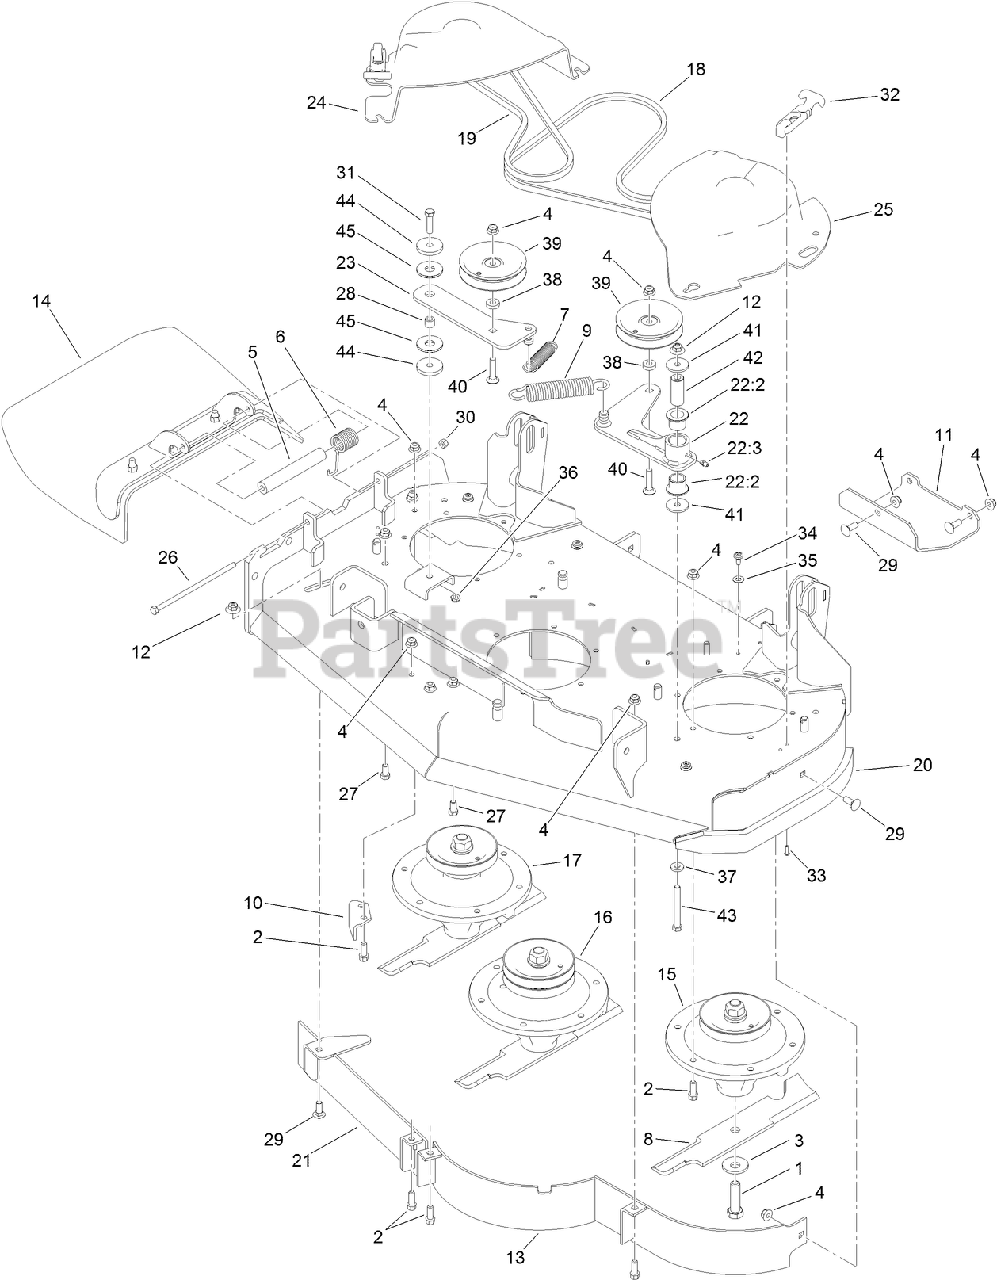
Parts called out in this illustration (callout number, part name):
1	SCREW-BLADE
2	SCREW-HWH
3	Washer-Blade Bolt, Heavy
4	NUT-HF, NI
5	SPACER
6	SPRING-TORSION
7	SPRING-EXTENSION
8	BLADE-14 INCH (HIGH SAIL)
9	SPRING-EXTENSION
10	BAFFLE-DISCHARGE
11	PLATE-SKID
12	NUT-FLANGE, NI
13	BAFFLE ASM
14	DEFLECTOR ASM
15	SPINDLE ASM
16	SPINDLE ASM
17	SPINDLE ASM
18	BELT-V
19	BELT-V
20	DECK AND DECAL ASM
21	FRONT BAFFLE ASM
22	IDLER ARM ASM
22:2	BUSHING
22:3	FITTING-LUBE, 45 DEG
23	IDLER ARM ASM
24	COVER-BELT, RH
25	COVER-BELT, LH
26	SCREW-HH
27	SCREW-HH
28	BUSHING-LEVER, LIFT
29	BOLT-CARR
30	NUT-LOCK, NI
31	SCREW-HH
32	LATCH-RUBBER
33	SCREW-HSBH
34	SCREW-SHOULDER
35	WASHER-THRUST
36	NUT-LOCK, NI
37	SPACER
38	SPACER
39	PULLEY-IDLER
40	SCREW-CARR
41	WASHER
42	SPACER-PLAIN
43	SCREW-HH
44	WASHER-PLAIN
45	WASHER-FRICTION, COMPOSITE
